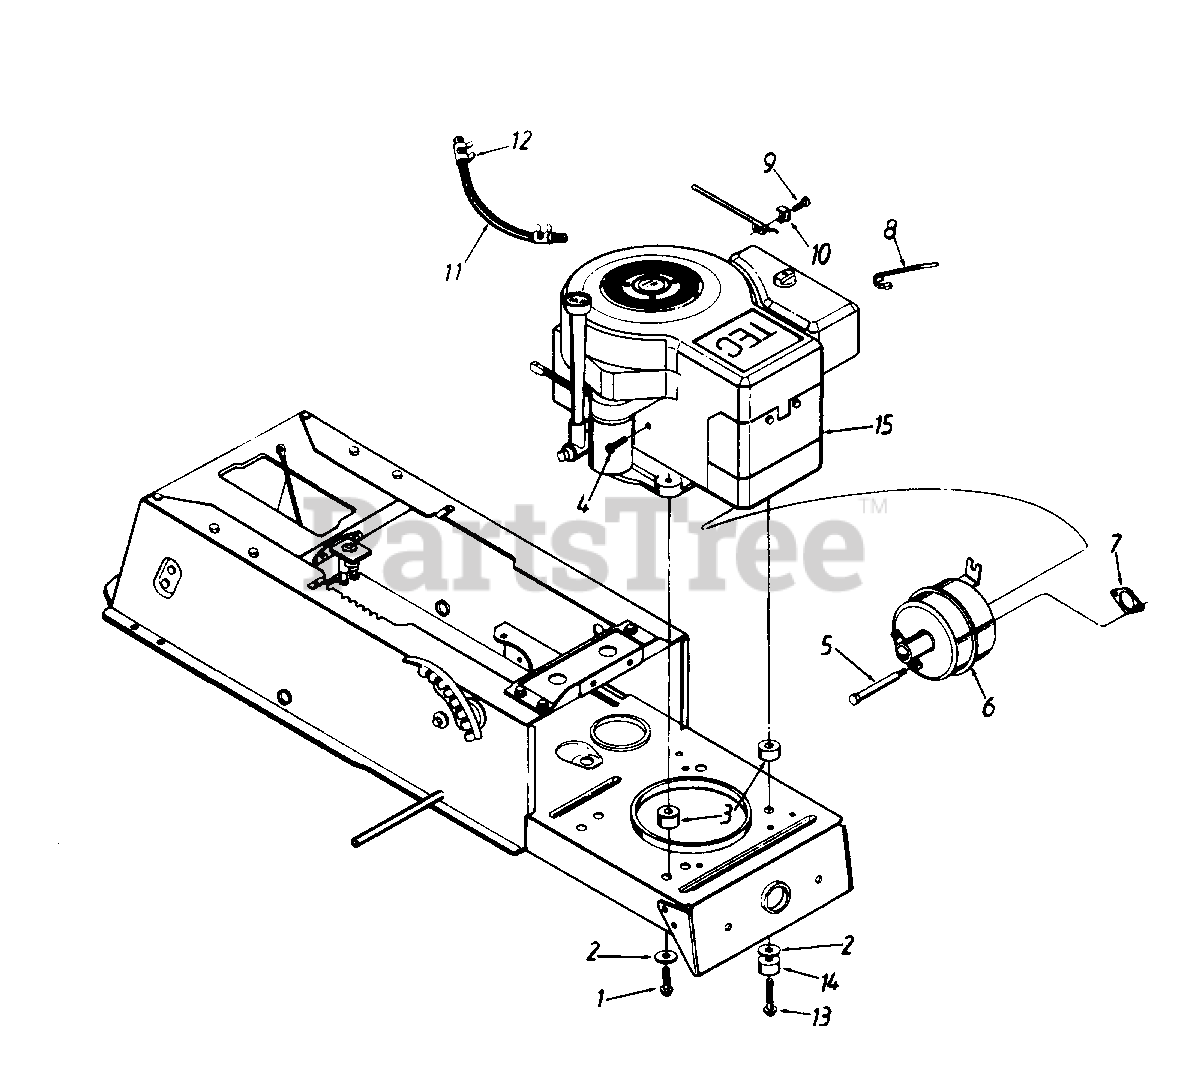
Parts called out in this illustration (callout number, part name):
1	Hex L-Wash. TT-Tap Scr. 3/8-16 x 1.5" Lg.
2	Fl-Wash. 3/8" I.D. x 1-1/4" O.D.
3	Shld. Spacer .38" I.D. x 1.25" O.D.
4	Pan Hd. Mach. Scr. 5/16-18 x .75" Lg.
5	Shld. Bolt 7/16" Dia. x 3-5/8" Lg. 12 & 12.5 H.P. Only
6	Muffler 12 & 12.5 H.P. Only
7	Exhaust Gasket 12 & 12.5 H.P. Only
8	Cable Tie
9	Hex Sems Scr. #10-32 x 5/8" Lg.
10	Casing Clamp
11	Fuel Line
12	Hose Clamp
13	Hex L-Wash. TT-Tap Scr. 3/8-16 x 2.5" Lg. 16 H.P. Only
14	Shld. Spacer .38" I.D. x 1.25" O.D. 16 H.P. Only
15	Engine
